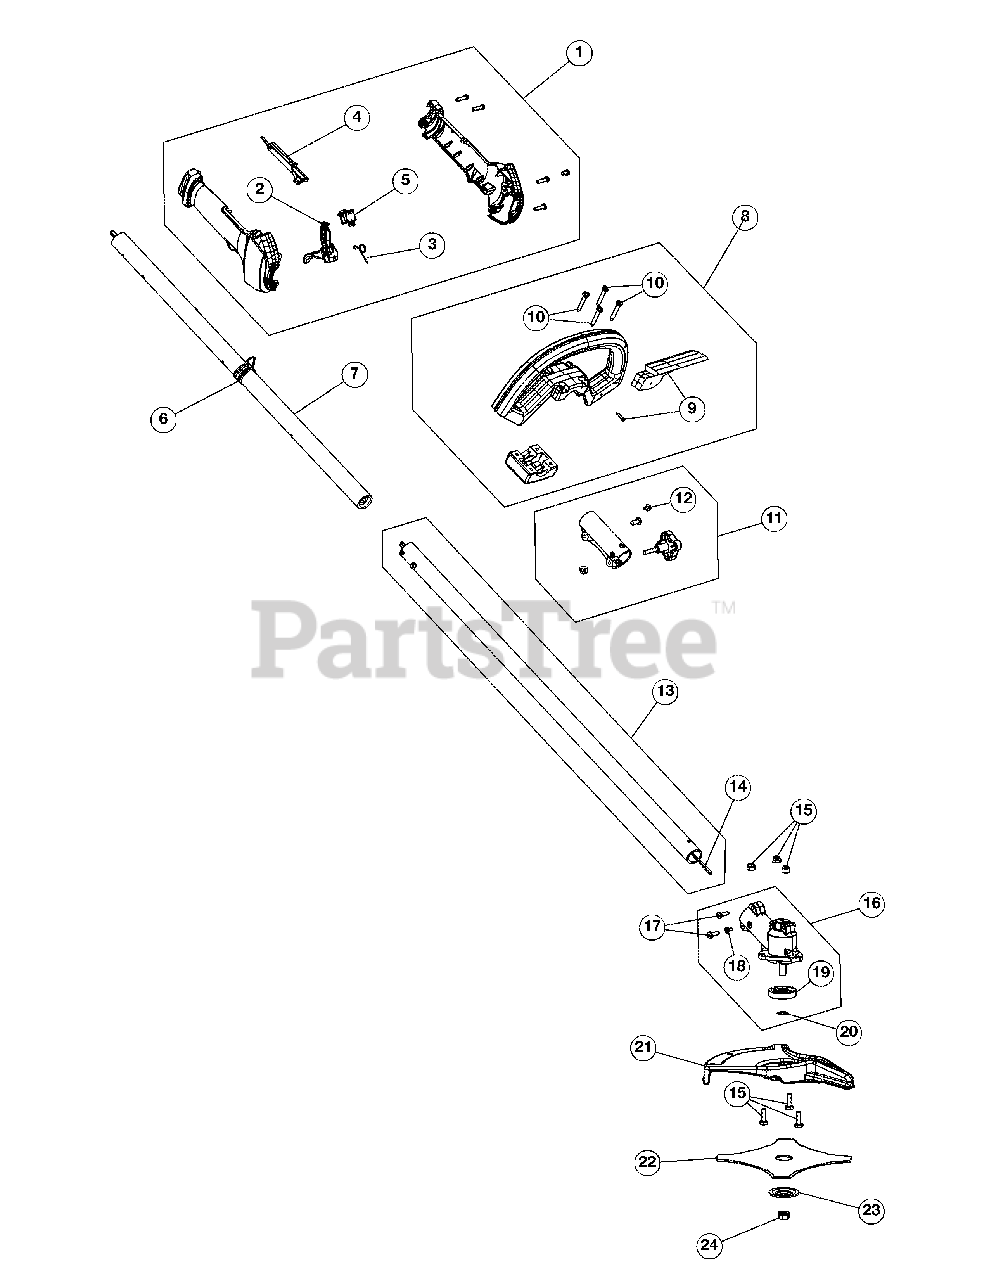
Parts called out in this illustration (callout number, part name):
1	Throttle Housing Assembly (Incl. 2-5)
2	Throttle Trigger
3	Spring
4	Throttle Lock-out
6	Shoulder Strap Clip
7	Upper Drive Shaft Housing Assembly
8	D-Handle Assembly (Incl. 9 & 10)
9	Barrier Bar Assembly
11	Split Boom Coupler (Incl. 12)
13	Lower Drive Shaft Housing Assembly
14	Lower Flexible Drive Shaft
15	Shield Mount Screw Assembly
16	2-Piece Gear Box Assembly (Incl. 17-20)
17	Gear Box Mounting Hardware
18	Anti-Rotation Screw
19	Blade Driver
20	Palnut
21	Blade Shield/Shield Mount
22	4-Tooth Blade
23	Retaining Washer
